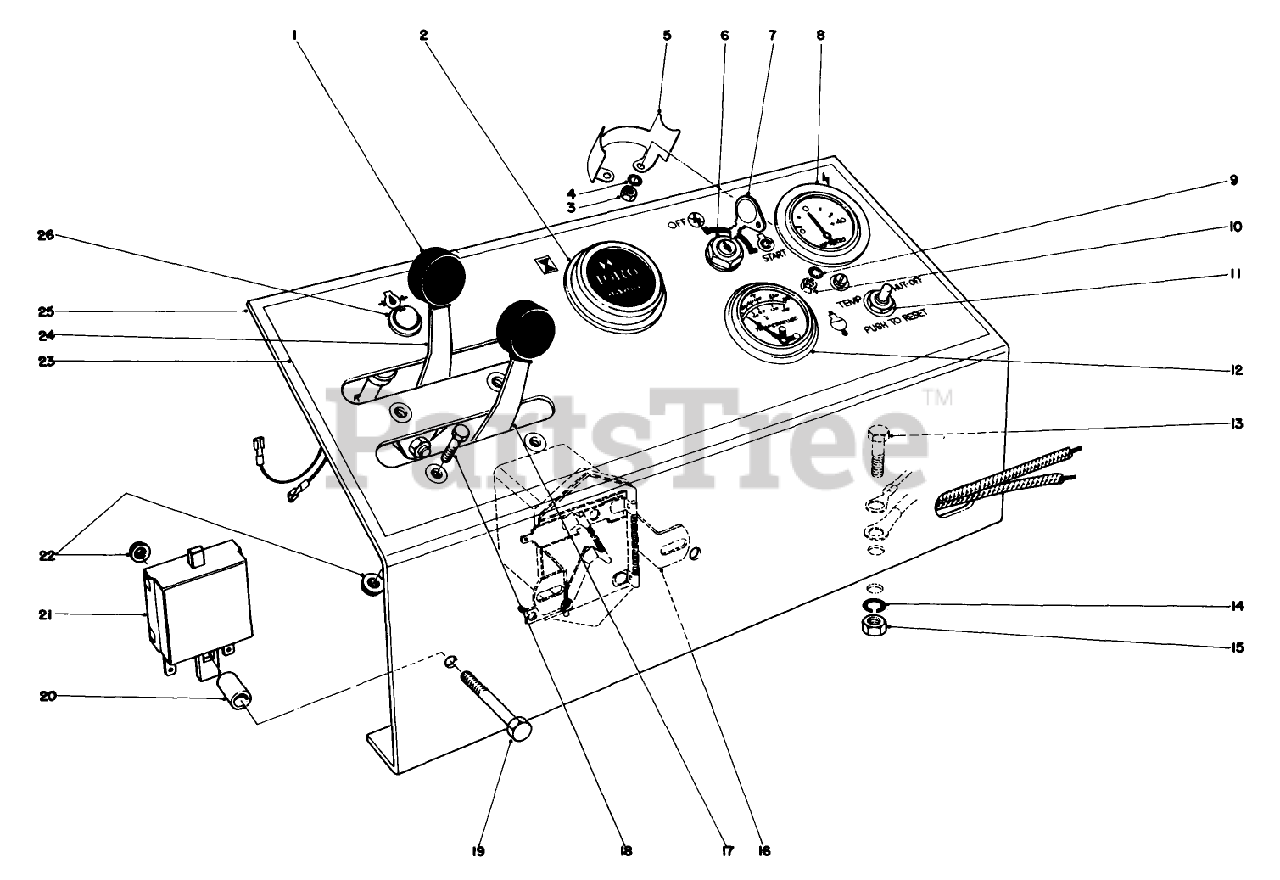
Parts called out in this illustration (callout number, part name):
2	HOUR METER
3	NUT-HEX
4	WASHER-LOCK
5	Clamp
6	SWITCH
7	Key
8	Ammeter
9	WASHER-LOCK, INTERNAL
10	NUT-HEX
11	TEMP RESET RELAY
12	ENG TEMP SWITCH GAGE
13	SCREW-HH
14	WASHER-LOCK
15	NUT-HEX
16	Regulator
17	Throttle Control (Incl. Ref. #1)
19	SCREW-HH
20	SPACER
21	BUZZER ASM
22	NUT-LOCK, FLANGE
23	Decal-Instrument Panel
24	Choke Control (Incl. Ref. #1)
25	INST PANEL B
26	Warning Light
